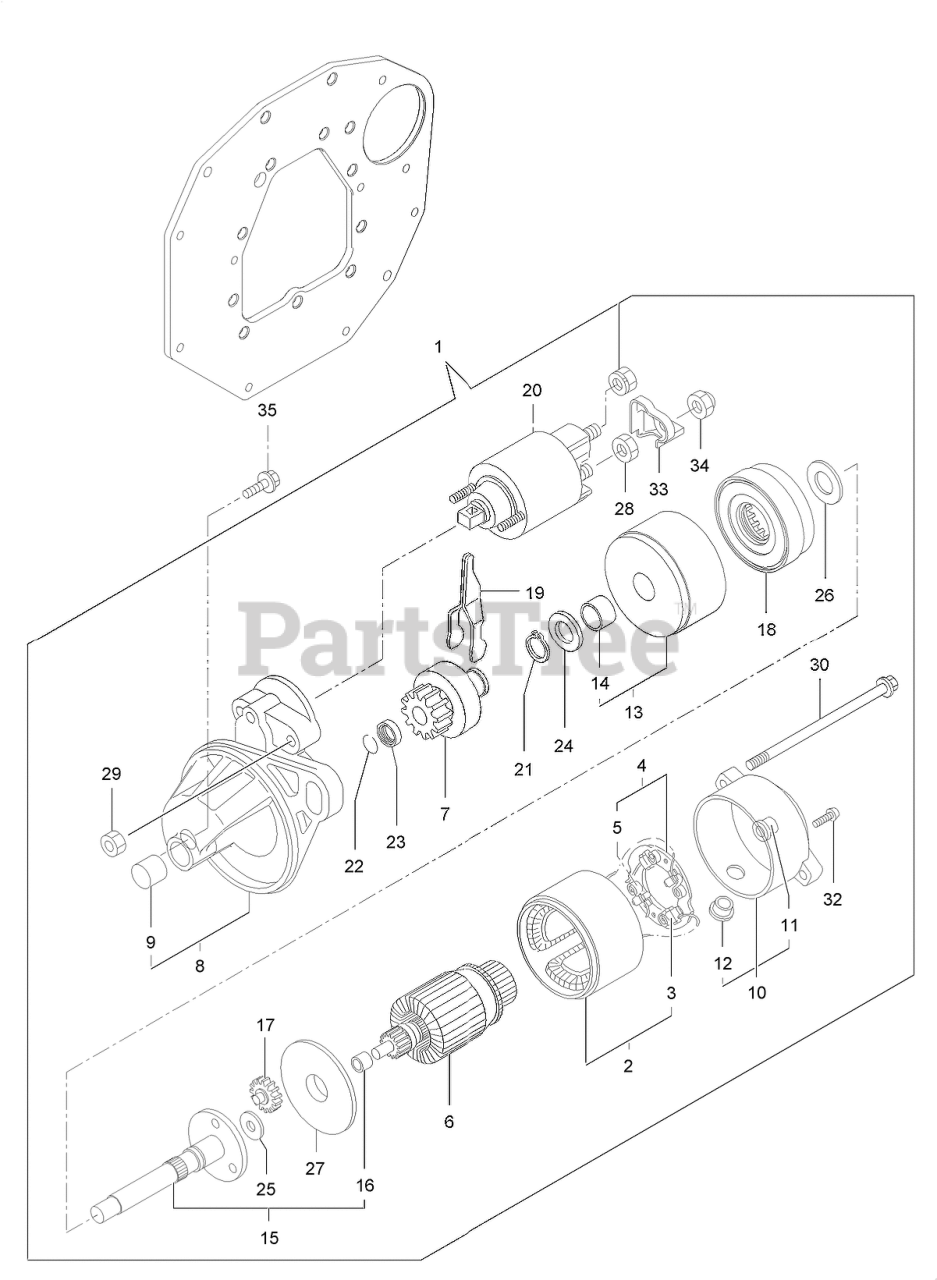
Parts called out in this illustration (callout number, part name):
1	STARTER ASM
2	YOKE ASM
3	STARTER KIT
4	HOLDER ASM
6	ARMATURE ASM
7	CLUTCH ASM
8	HOUSING ASM
9	BEARING, NEEDLE 1
10	FRAME ASM
11	BEARING
13	BEARING ASM
14	Bearing
15	SHAFT ASSY 1
16	Bearing
20	SWITCH ASM
30	BOLT-THROUGH
33	COVER-TERMINAL
